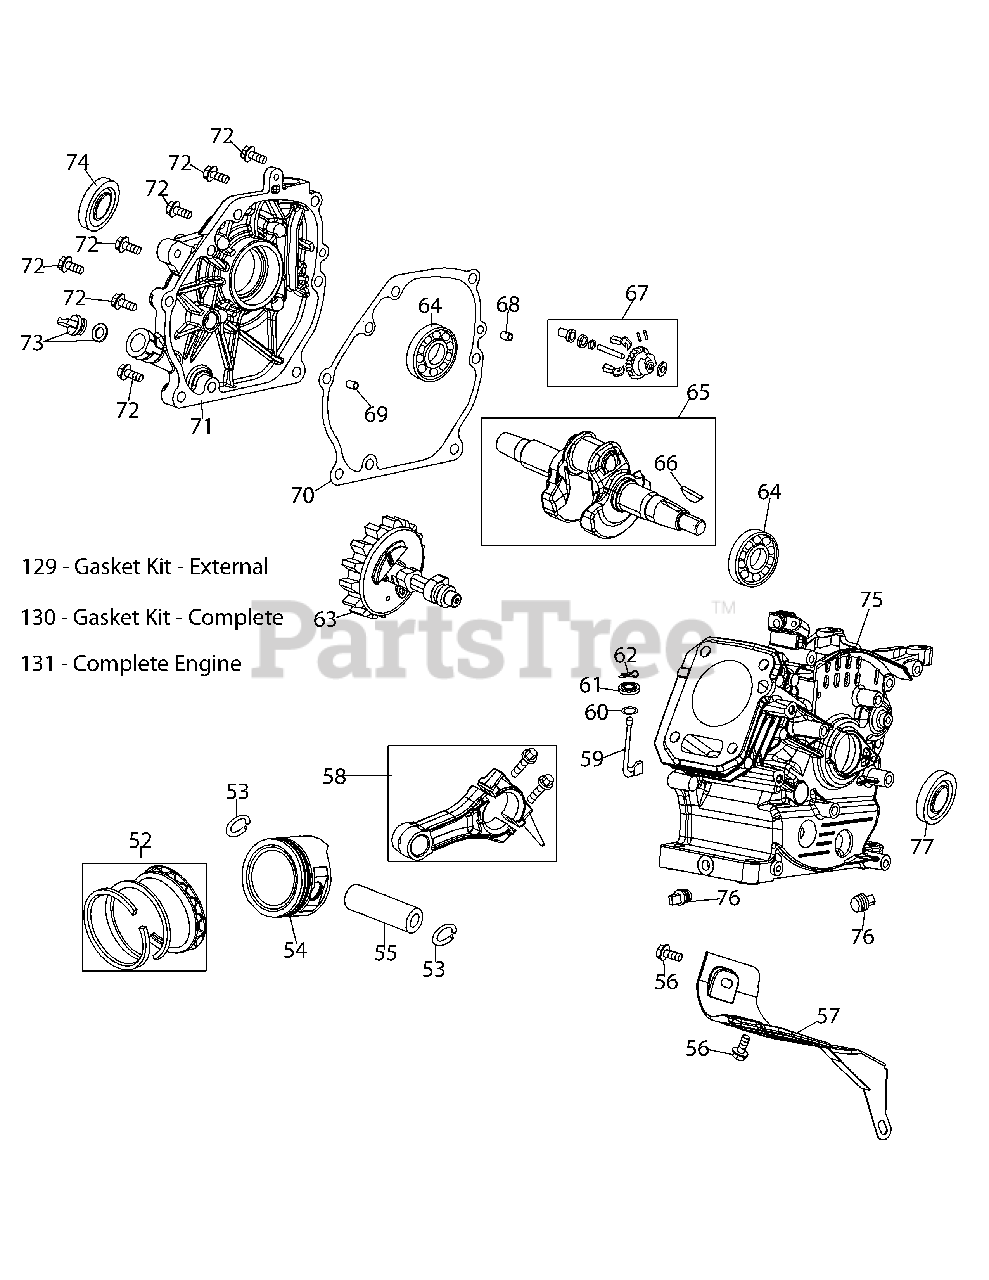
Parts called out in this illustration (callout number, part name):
52	Piston Ring Set
53	Piston Pin Snap Ring
55	Piston Pin
56	Bolt M6×12
57	Air Shield
58	Connecting Rod Assembly
59	Governor Arm Shaft
60	Washer 5.2×1.9
61	Governor Seal
62	Cotter Pin
63	Camshaft Assy.
64	Radial Ball Bearing, 6205
65	Crankshaft Assembly
66	Woodruff Key
67	Governor Gear/Shaft Assembly
68	Dowel Pin 7×14
69	Dowel Pin 9×14
70	Crankcase Cover Gasket
71	Cover Comp, Left Crankcase
72	Bolt M8×32
74	Oil Seal, 25×41.25×6
75	Short Block
76	Oil Drain Plug
77	Oil Seal 25×41.25×6
129	Gasket Kit - External
130	Gasket Kit - Complete
131	Complete Engine
